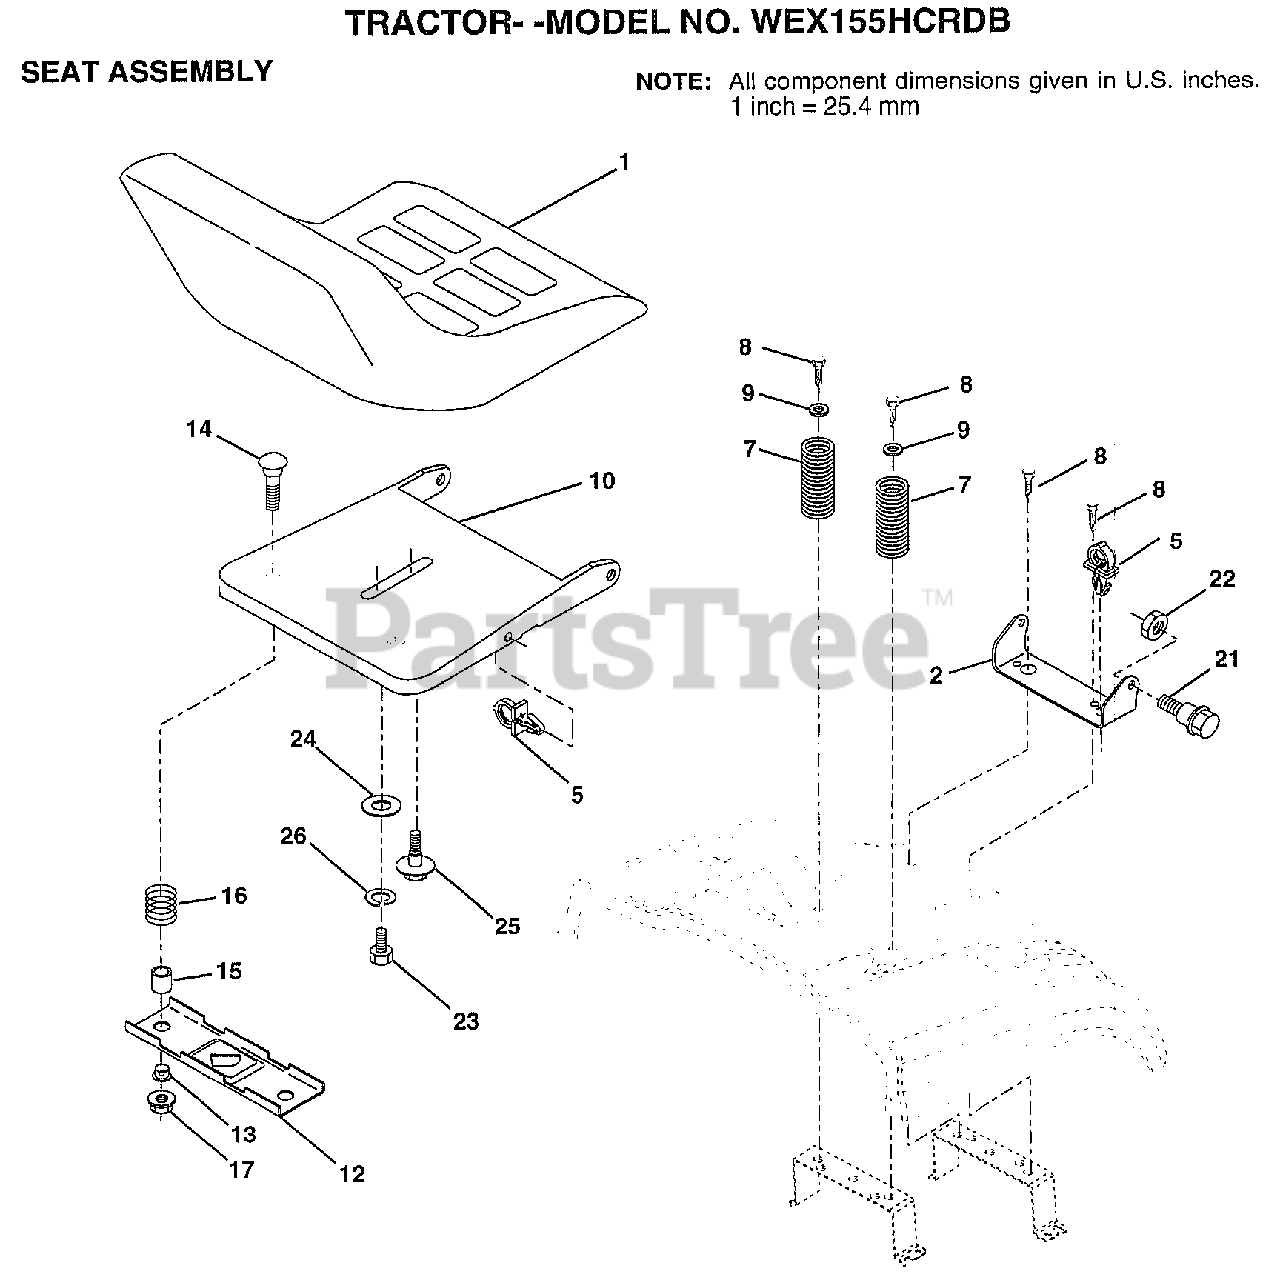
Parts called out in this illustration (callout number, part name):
2	BRACKET PVT SEAT
5	CLIP.PUSH-IN.HING
7	SPRING COMPRESSIO
8	SCREW GTV
9	WASHER
10	PAN-SEAT
12	BRKT SWITCH
13	BUSHING
14	BOLT-RD HD SQ NK
15	SPACER SPLIT
16	SPRING COMPRESSED
21	"BOLT,SHOULDER"
22	NUT
23	BOLT
24	WASHER
25	"BOLT,SHOULDER"
26	LOCKWASHER
